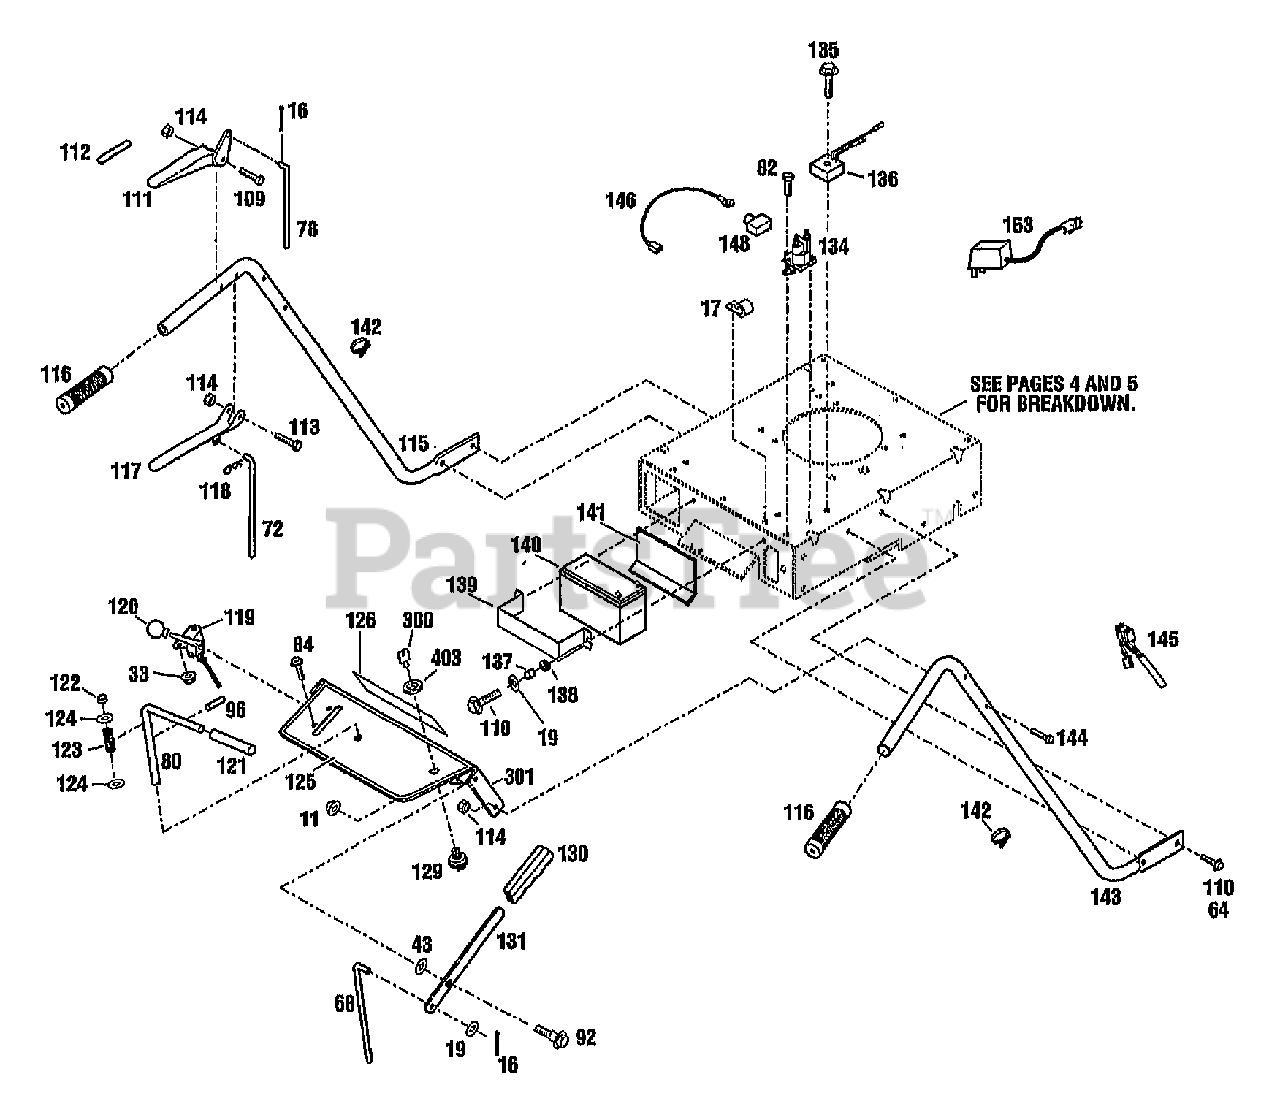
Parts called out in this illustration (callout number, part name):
11	NUT-HFLK 3/8-16 ZP
16	PIN-COTTER .093X.625
17	CLIP-CLAMP .25 ID
19	WASHER-FLAT 5/16 SAE
33	NUT-HF/LK 1/4-20 ZP
43	WASHER-FLAT 1.0X.516X.031
64	NUT-HFLK 5/16-18 ZP
68	ROD-UPPER BLADE
72	ROD-UPR TRANSMISSION
78	ROD-UPPER BRAKE
80	LEVER-SHIFT
82	SCR 1/4-20X.5 FL SELF TAP {34071,34074}
84	SCR-HFLK 1/4-20X.50 ZP
92	BOLT-SHOULDER MOWER
96	PIN-ROLL .25X2.25
109	SCR-HH 1/4-20X1.75 G5 ZP
110	SCR-HFLK 5/16-18X.75 ZP
111	LEVER-CONTROL
112	DECAL-OPC MOWERS
113	SCR-HH 1/4-20X1.5 G5ZP
114	NUT-HT LK 1/4-20
115	HANDLEBAR-LH
116	GRIP-FLEX
117	HANDLE-CONTROL MOWER
118	PIN-CLIP .08
119	CABLE-THROTTLE CONTROL
120	KNOB
121	GRIP-HANDLE
122	BUSHING-.5X.21 NYLON FLNG
123	SPRING-COMPRESSION
124	WASHER-1.06X.531X.1 ZP
125	DECAL-WARNING STD WC {34073,34075}
125	DECAL-WARNING ELEC WC {34071,34074}
126	DECAL-WIDE CUT T/B
129	ASSM-KEYSWITCH {34071,34074}
130	GRIP-HANDLE
131	LEVER-MOWER ENGAGE ZP
134	SOLENOID {34071,34074}
135	SCR-HFLK {34071,34074}
136	REGULATOR
137	SPACER {34071,34074}
138	GROMMET {34071,34074}
139	BRACKET-BATTERY {34071,34074}
140	BATTERY {34071,34074}
141	PAD-BATTERY {34071,34074}
142	TIE-CABLE NYLON BLACK
143	HANDLEBAR-RH
144	SCR-HH 1/4-20X1.75 G5 ZP
145	HARNESS-WIRING {34071,34074}
146	ASSM-WIRE LEAD {34071,34074}
148	BOOT-CABLE {34071,34074}
153	CHARGER-BATTERY {34071,34074} (SHIPPED LOOSE)
300	KEY-IGNITION {34071,34074}
301	ASSM-CONSOLE {34073,34075} (INCL. 125)
301	ASSM-CONSOLE {34071,34074} (INCL. 125)
403	NUT-IGNITION SWITCH
